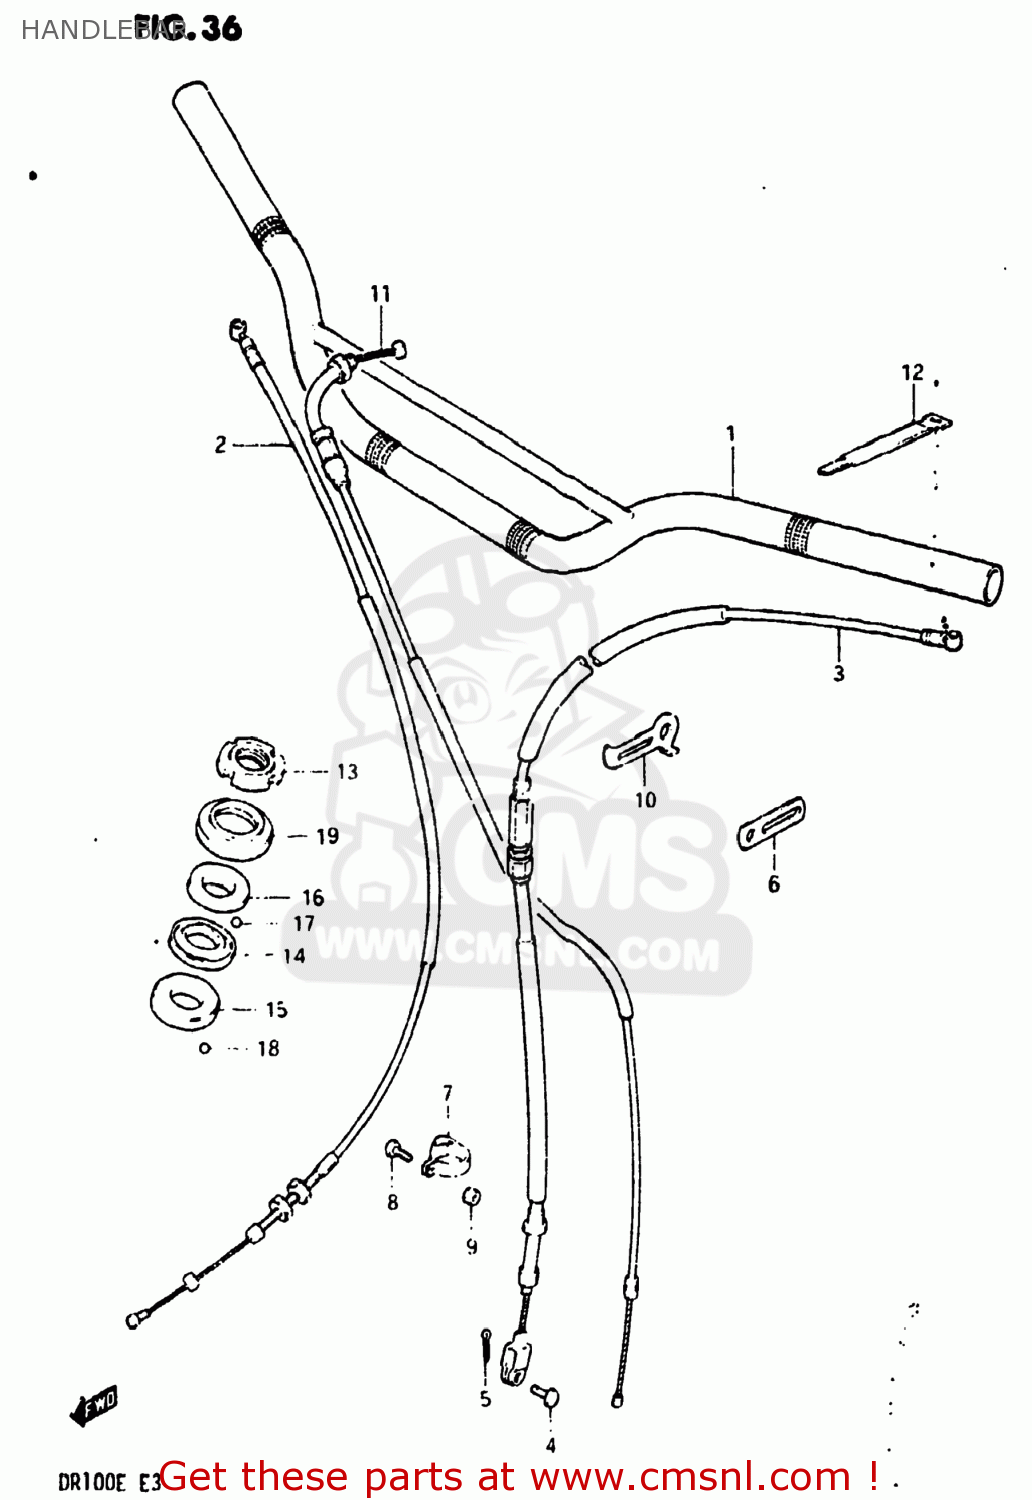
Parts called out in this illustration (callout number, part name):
1	HANDLEBAR
2	CABLE,FR BRAKE
3	CABLE ASSY,CLUTCH
4	PIN(L:15)
5	PIN
6	CLAMP
7	CLAMP,CABLE
8	SCREW
9	NUT
10	CLAMP,CABLE
11	CABLE ASSY,THROTTLE
12	CLAMP
13	NUT,STEERING STEM(25X44X10)
14	RACE,STEERING INNER UPR
15	LACE,STEERING INNER LWR
16	RACE,STEERING OUTER UPR
17	BALL
18	BALL
19	DUST SEAL,STEERING UPR
